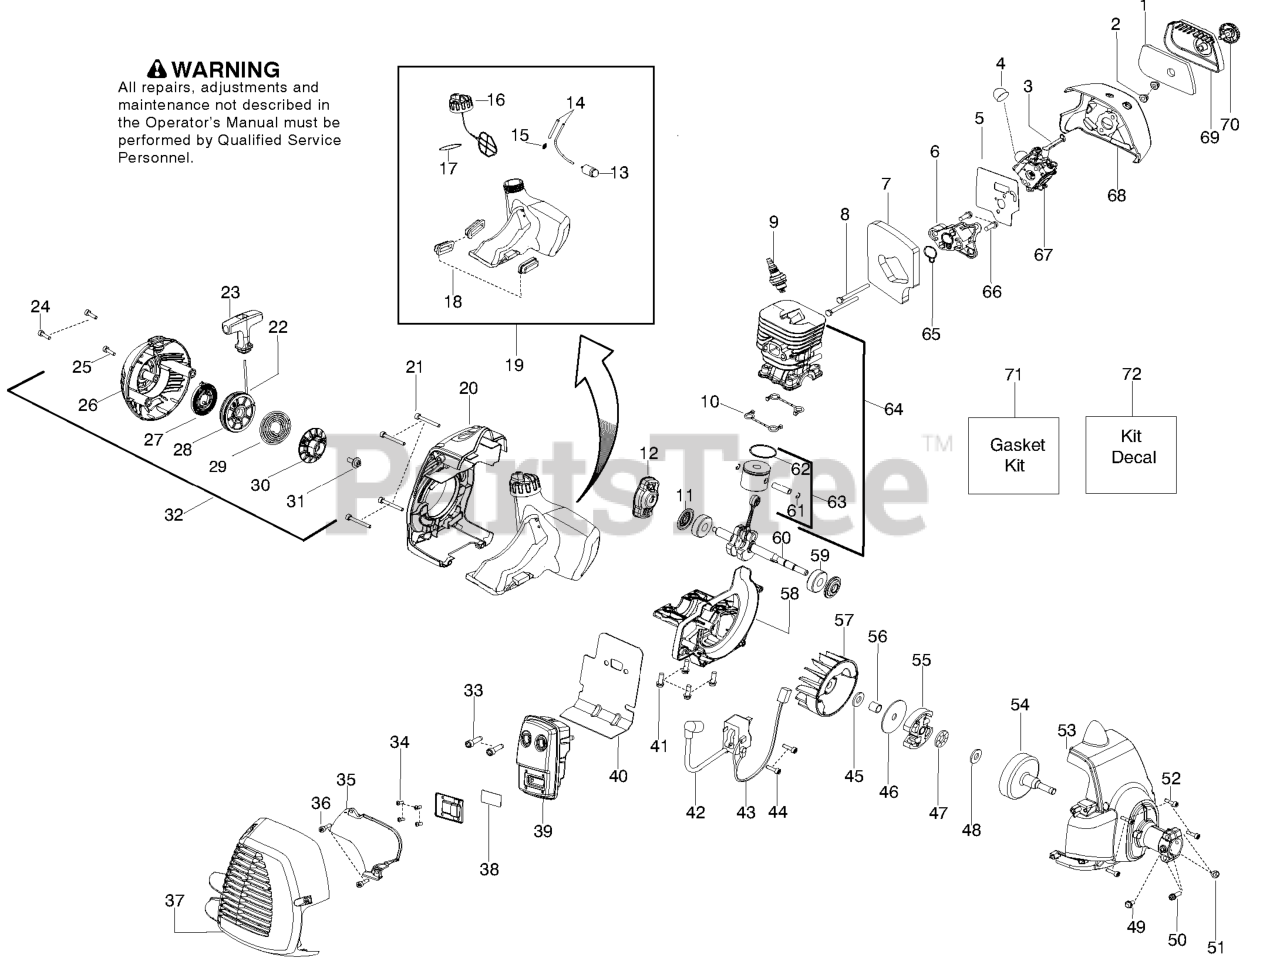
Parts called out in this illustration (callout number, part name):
1	FILTER AIRBOX
3	CHOKE LEVER
4	PURGE BULB ZAMA
5	KIT GASKET CARB 28CC
6	CARB ADAPTOR
7	KIT GASKET 28CC
8	BOLT CARB ADAPTOR
9	Plug-Spark (RCJ-8Y)
10	KIT GASKET 28CC
11	KIT GASKET 28CC
12	STARTER PAWL BRIDGE
13	FUEL PICK-UP ASSY
14	KIT-LINE(FUEL)
15	FUEL LINE FITTING
16	ASSY-CAP W/RETAINER
17	KIT GASKET 28CC
18	ISOLATOR FUEL TANK
19	KIT FUEL TANK HVA
20	REAR SHROUD ORANGE
22	KIT ROPE
23	STARTER HANDLE
24	SCREW M5-0.8X30MM
25	SCREW M4 X 1.75 PT 16MM
26	KIT STARTER HSG HVA 128
27	KIT STARTER SPRING
28	KIT STARTER PULLEY
29	SPRING - DRIVER
30	DRIVER PULLEY
32	ASSY STARTER HSG HVA
33	BOLT MUFFLER
34	SCREW-6-19X5/16PLAST PA
35	SHIELD HEAT
36	SCREW M4 X 1.75 PT 16MM
37	KIT MUFFLER GUARD HVA
38	KIT SPARK ARRESTOR SCREEN
39	KIT MUFFLER LE28
40	KIT GASKET 28CC
41	SCREW-M5-0.8 X 25MM(TAP)
42	IGNITION MODULE MBU-7
43	ASSY MODULE LEAD WIRE
44	SCREW M4 X .70 TT 16MM
45	WASHER CLUTCH
46	WASHER-CLUTCH
47	BEARING THRUST
48	WASHER THRUST
49	SCREW-10-14 X 1/2 PLASTITE
50	SCREW-10-24 X 1" (UNC)
51	LOCKNUT-HEX 10-24
52	SCREW M4 X .70 TT 16MM
53	ASSY FAN HOUSING HVA 1"
54	ASSY-CLUTCH DRUM
55	ASSEMBLY CLUTCH
56	SPACER FLYWHEEL
58	CRANKCASE CAST LE28
59	BEARING RADIAL BALL (6201)
60	ASSY CRANKSHAFT
61	WRIST PIN RET.
62	RING PISTON
63	KIT - PISTON
64	KIT PISTON CYL
65	KIT GASKET 28CC
66	SCREW-M5-0.8 X 25MM(TAP)
67	KIT CARB
68	AIRBOX HVA 128 HUSKY GRAY
69	COVER-AIR BOX
70	KNOB ASSY AIRBOX COVER
71	KIT GASKET 28CC
